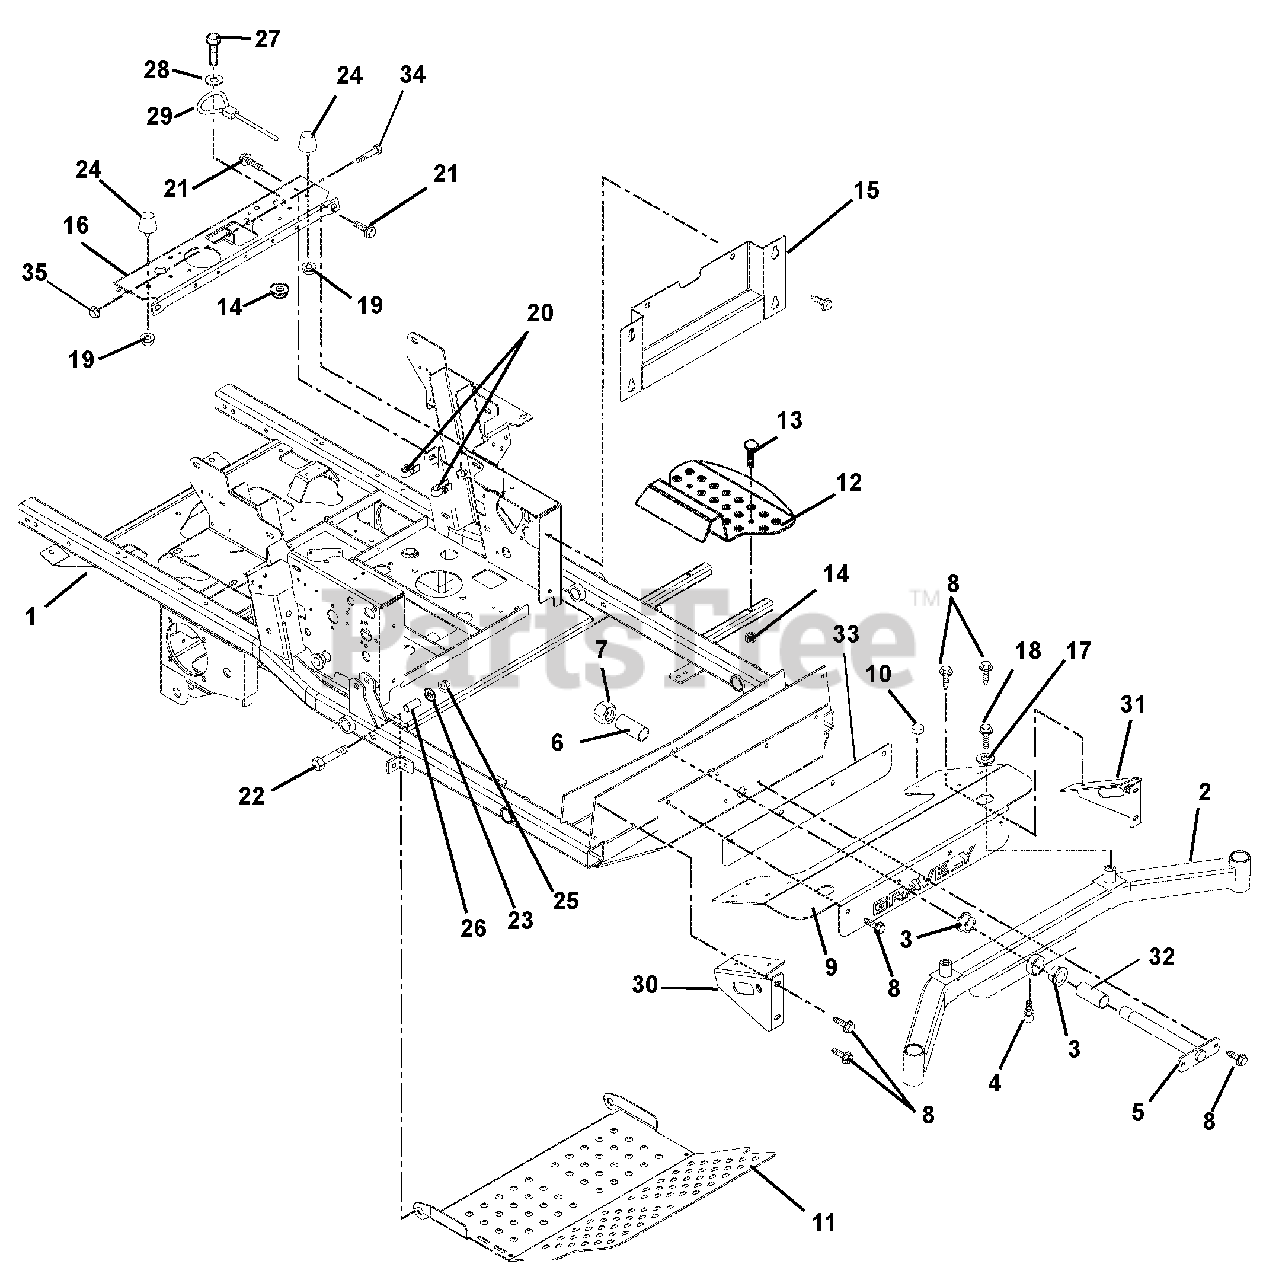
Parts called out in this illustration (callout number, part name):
1	Weldment, Frame
2	Weldment, Axle
3	Bushing, Flange 1.25 x 1.50 x 1.00 x .200
4	Fitting, Lube 45 Degree GM411031
5	Pin, Axle
7	Nut, Locking Nylon 1.00-14
8	Screw, Tapping .38-16 x .75
9	Axle Cover
10	Button, Rubber
11	Panel, Inspection
12	Step, Ingress
13	Bolt, Round Head Square Neck .31-18 x 1.75 Grade 5
14	Nut, Locking Top Flange .31-18
15	Plate, Kick
16	Channel, Cross
17	Washer, Flat Steel .640 x 1.81 x .25
18	Bolt, Hex .50-20 x 1.00 Grade 5
19	Nut, Locking Flange .312-18
20	Nut, Retainer .375-16 x .37
21	Bolt, Serrated Hex Flange Washer Head .38-16 x 1.00
22	Bolt, Hex .50-13 x 3.25 Grade 5
23	Washer, Flat Steel .563 x 1.38 x .109
25	Nut-Locking-Top-Flange .50-13
26	Bushing, Flange .515 x .75 x .275 x 1.12
27	Bolt, Hex .31-18 x .75 Grade 5
28	Washer, Flat Steel .344 x 1.25 x .135
29	Cable, Seat Prop.
30	Weldment, RH Axle Cover Support
31	Weldment, LH Axle Cover Support
32	Spacer, 1.25OD x 1.0ID x 3.63
33	Plate, Backer
34	Bolt, Hex .38-16X3.00 Grade 5
35	Nut, Locking-Top-Flange .38-16
